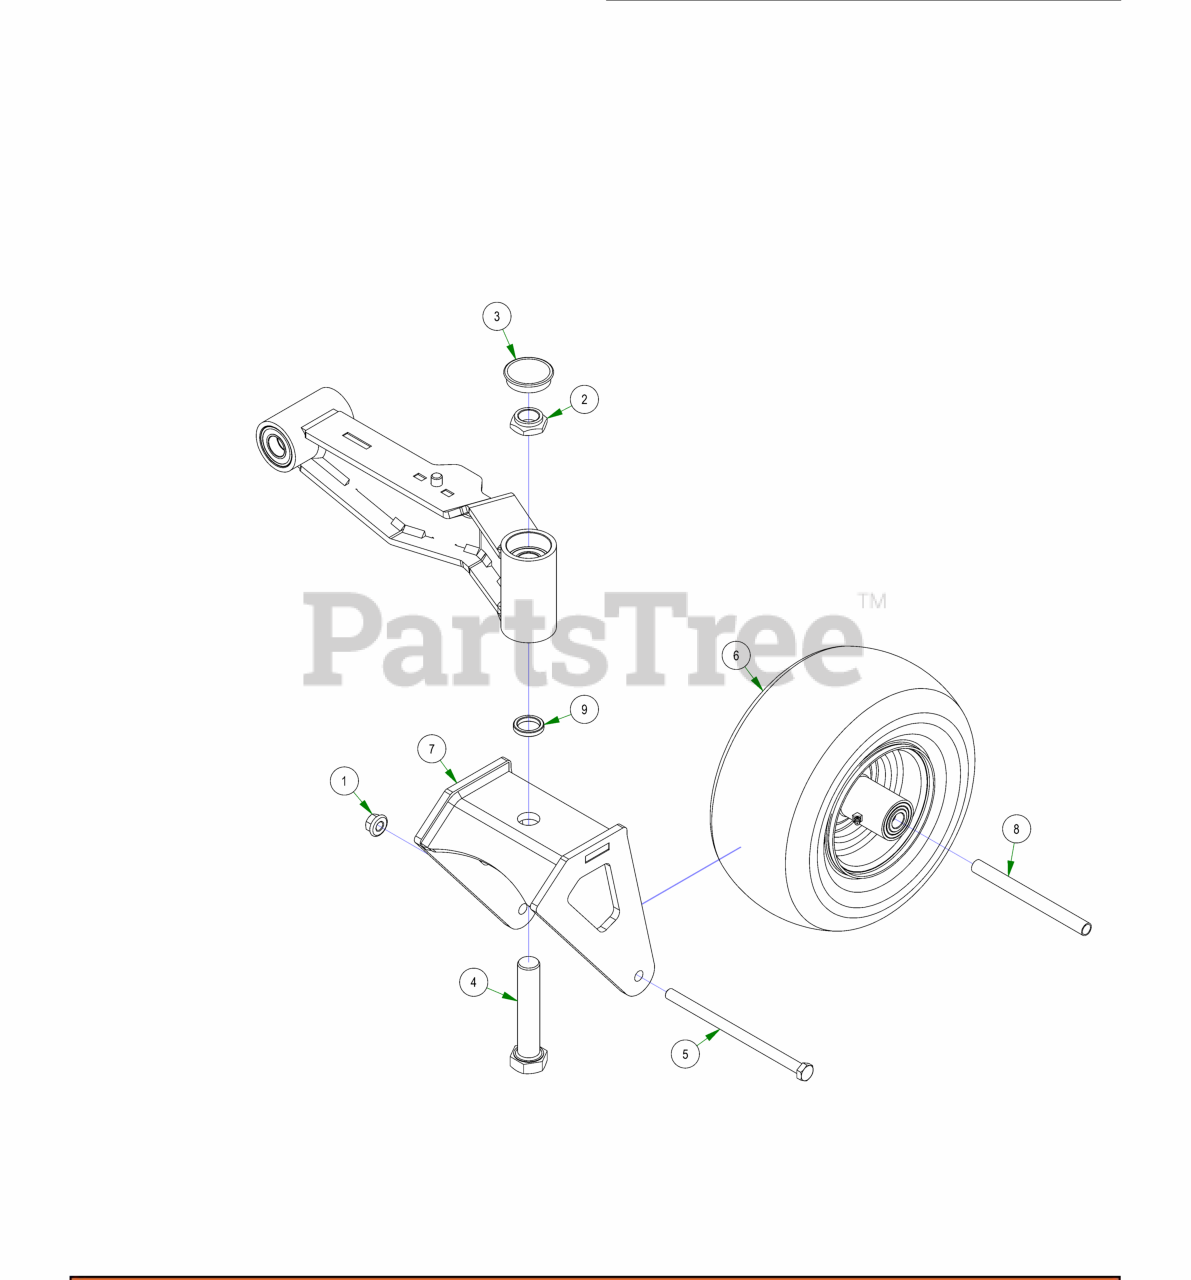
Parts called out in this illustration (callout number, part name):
1	1/2-13 NYLON INSERT FLANGE LOCKNUT ZINC
2	1"-14 NYLON INSERT JAM LOCKNUT ZINC
3	2017 Bearing Cover
4	1"-14 X 5 HEX CAP SCREW (GR.8) ZINC YELLOW
5	1/2-13 X 8-1/2 HEX CAP SCREW (GR.5) ZINC
6	13x6.50-6 Black No Flat Assembly
7	2019 Stand-on Front Fork Weldment
8	Front Wheel Spanner
9	Spacer, 1x1.375x.25
